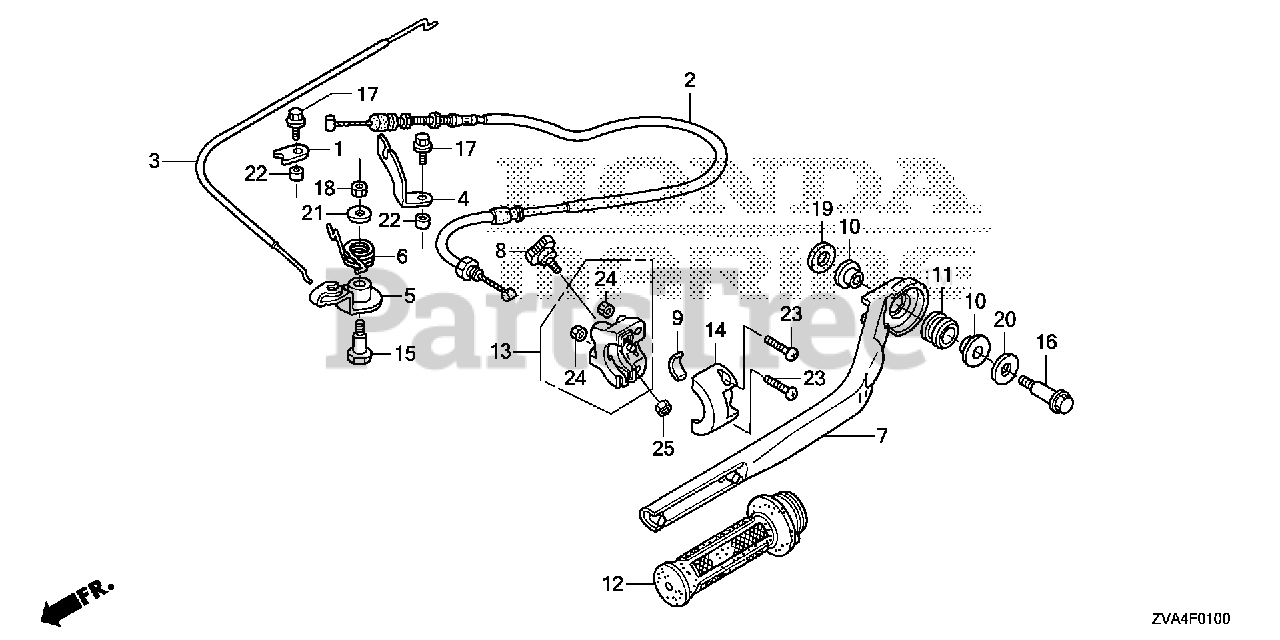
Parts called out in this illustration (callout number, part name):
1	HOLDER, CABLE
2	CABLE A, THROTTLE
3	CABLE B, THROTTLE
4	HOLDER, CABLE
5	ARM, THROTTLE
6	SPRING, THROTTLE ARM
7	HANDLEBAR *NH246* (LOOSY GRAY)
8	BOLT, FRICTION
9	BLOCK, THROTTLE FRICTION
10	COLLAR, HANDLE MOUNTING
11	RUBBER, HANDLE MOUNTING
12	GRIP, THROTTLE
13	HOUSING, THROTTLE (LOWER)
14	HOUSING, THROTTLE (UPPER)
15	BOLT, HEX. (6X24)
16	BOLT, SPECIAL (8X42)
17	BOLT, FLANGE (6X12)
18	NUT, HEX. (6MM)
19	WASHER, PLAIN (8MM)
20	WASHER (32MM)
21	WASHER, PLAIN (6MM)
22	COLLAR (6.2X8.5X5)
23	SCREW-WASHER (5X20)
23	SCREW-WASHER (5X22)
23	SCREW, PAN (5X20)
24	NUT, HEX. (5MM)
25	NUT, HEX. (6MM)
